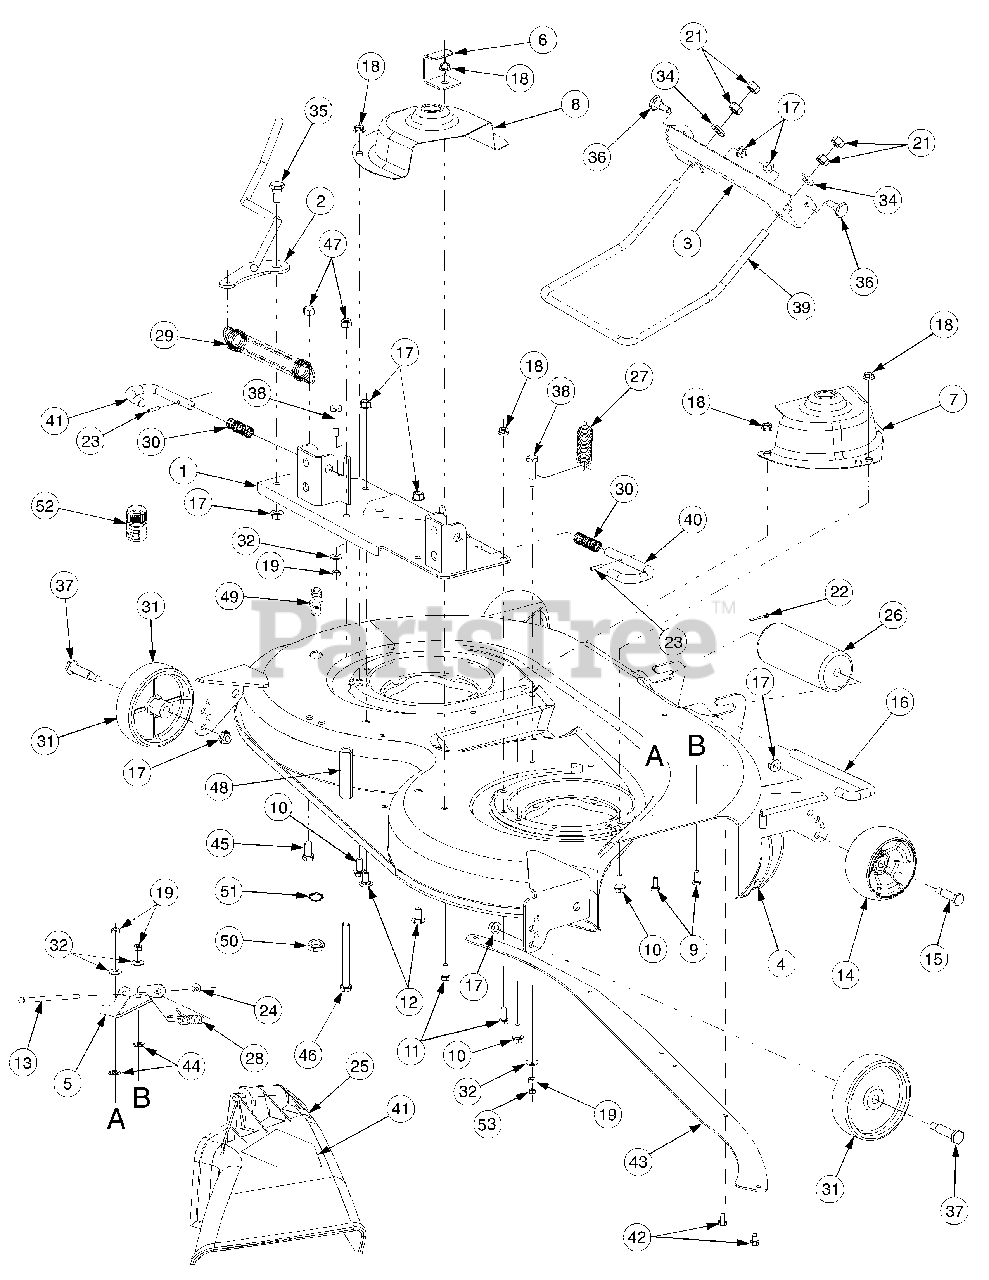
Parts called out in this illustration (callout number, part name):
4	Deck Assembly, 42"
4	Graphic, Danger Top/RH Deck
4	Graphic, Tension Lever
4	Graphic, Safety Top/LH Deck
4	Graphic, Belt Routing
4	Graphic, 42" Cut
4	Graphic, Cut
4	Graphic, Deck Wash
5	Bracket, Hinge Mounting
9	Screw, Hex Cap, 1/4-20 x .62 GR5
10	Screw, Hx Wsh Hd Tapp, 5/16-18 x .75
11	Screw, Hex Cap, 5/16-18 x .75 GR5
12	Bolt, Carriage, 3/8-16 x .75
13	Pin, Hinge, .25 Dia x 6.75 Lg
14	Wheel, Deck w/Fitting
15	Bolt, Shoulder, 1/2 x 2.5 : 3/8-16
16	Pin, Roller, 1/2 Dia x 7.31 Lg
17	Nut, Hex Flange Lock, 3/8-16
18	Nut, Hex Flange Lock, 5/16-18 GR5
19	Nut, Hex, 1/4-20
21	Nut, Hex, 1/2-13
22	Pin, Cotter, 3/32 x 1.25
23	Pin, Spirol Spring, 3/16 x .75
24	Cap, Speed Nut
25	Deflector Assy, Includes 5, 13, 24, 28, and 44
26	Roller
27	Spring, Extension, .88 OD x 6.12
28	Spring, Torsion
29	Spring, Extension, 1.25 OD x 8.15
30	Spring, Compression
31	Wheel, Deck, 5 in. Dia
32	Washer, Bell, .265 x .75 x .062
34	Washer, Flat, .531 x 1.062 x .134 HT
35	Bolt, Shoulder, .498 Dia x .340 Lg
36	Bolt, Shoulder, .50 Dia x .434 Lg
37	Bolt, Shoulder, 1/2 x 1.5 : 3/8-16
38	Bolt, Shoulder, .375 Dia x 1.16 Lg
39	Rod, Front Lift
40	Pin, Mower Support
41	Graphic, Danger
42	Screw, Self Tapping, 1/4-20 x .5
43	Skirt, Deck
44	Nut, Push, 1/4
45	Screw, Hx Cap Lock, 3/8-24 x .75 GR5
46	Screw, Hex Cap, 3.8-24 x 3.75 GR5
47	Nut, Hex Insert Lock, 3/8-24
49	Nozzle, Deck Wash
50	Nut, Hex, M16-1.5
51	Washer, Lock
52	Adapter, Water Nozzle
53	Nut, Hex Flange Lock, 1/4-20 GrF
